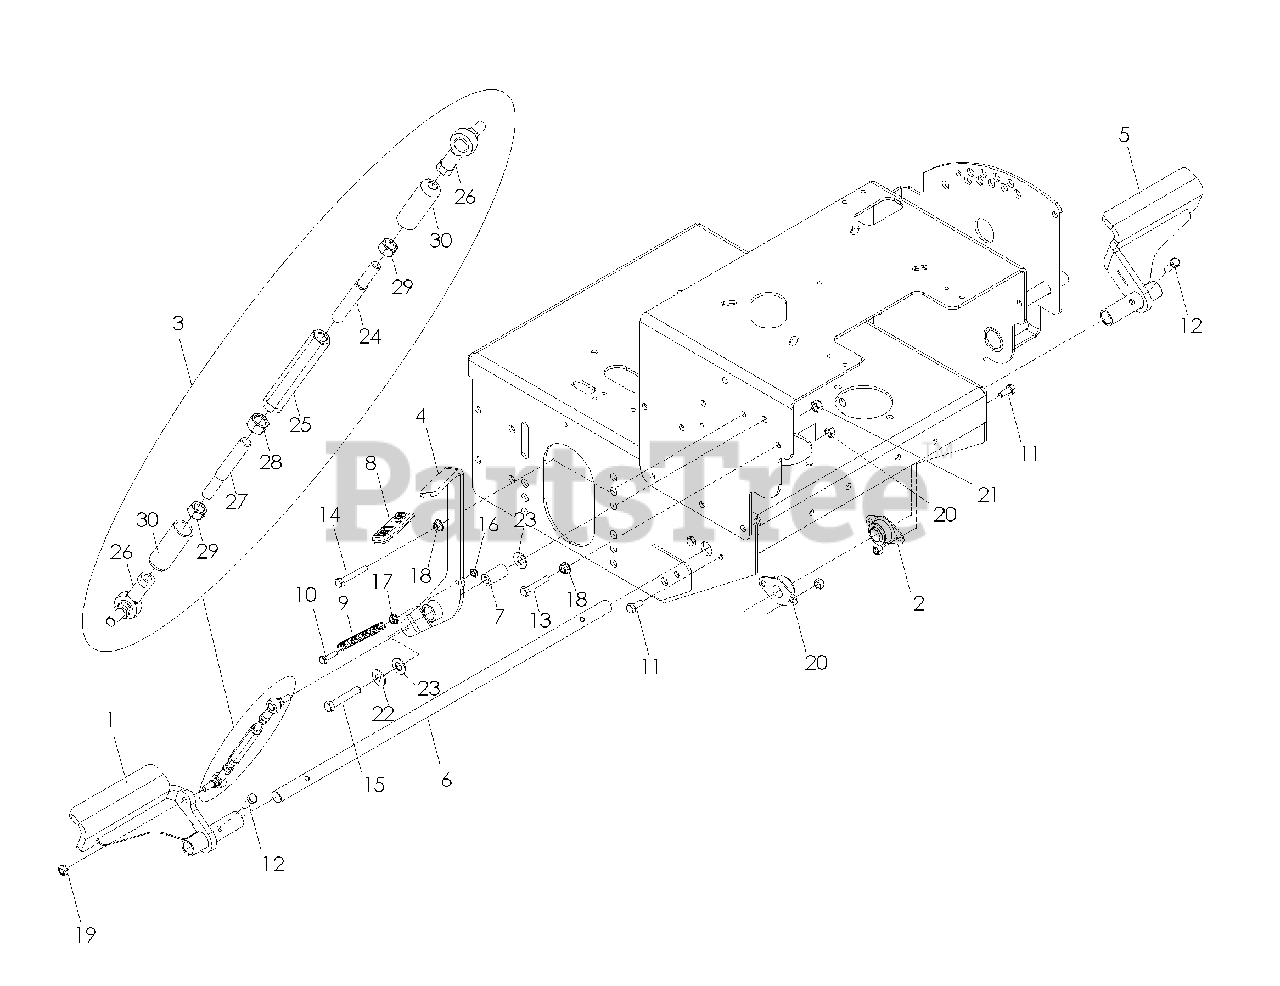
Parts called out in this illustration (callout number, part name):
1	SNUBBER, LEFT
2	FLANGE BEARING
3	LINKAGE, BRAKE
4	ARM, BRAKE
5	SNUBBER, RIGHT
6	SHAFT, BRAKE
8	GRIP, PARK BRAKE
10	HCS 1/4-20 x 1
11	HCS 5/16-18 x 3/4
12	HCS 5/16-18 x 1
13	HCS 5/16-18 x 1 3/4
14	HCS 5/16-18 x 2
15	HCS 3/8-16 x 2
16	NUT 1/4-20 THIN NYLOC
17	NUT 1/4-20 WHIZLK
18	NUT 5/16-18 WHIZLK
19	NUT 5/16-18 HEX CTRLK
20	NUT 5/16-18 HEX NYLOC
21	NUT 3/8-16 HEX NYLOC
22	WASHER 3/8 FLAT
23	WASHER 7/16 SPRING
24	LINKAGE, RH
25	TURNBUCKLE 3/8
26	SPHERICAL ROD END RH
27	LINKAGE, LH
28	NUT 3/8-24 HEX GR2
29	NUT 5/16-24 HEX
